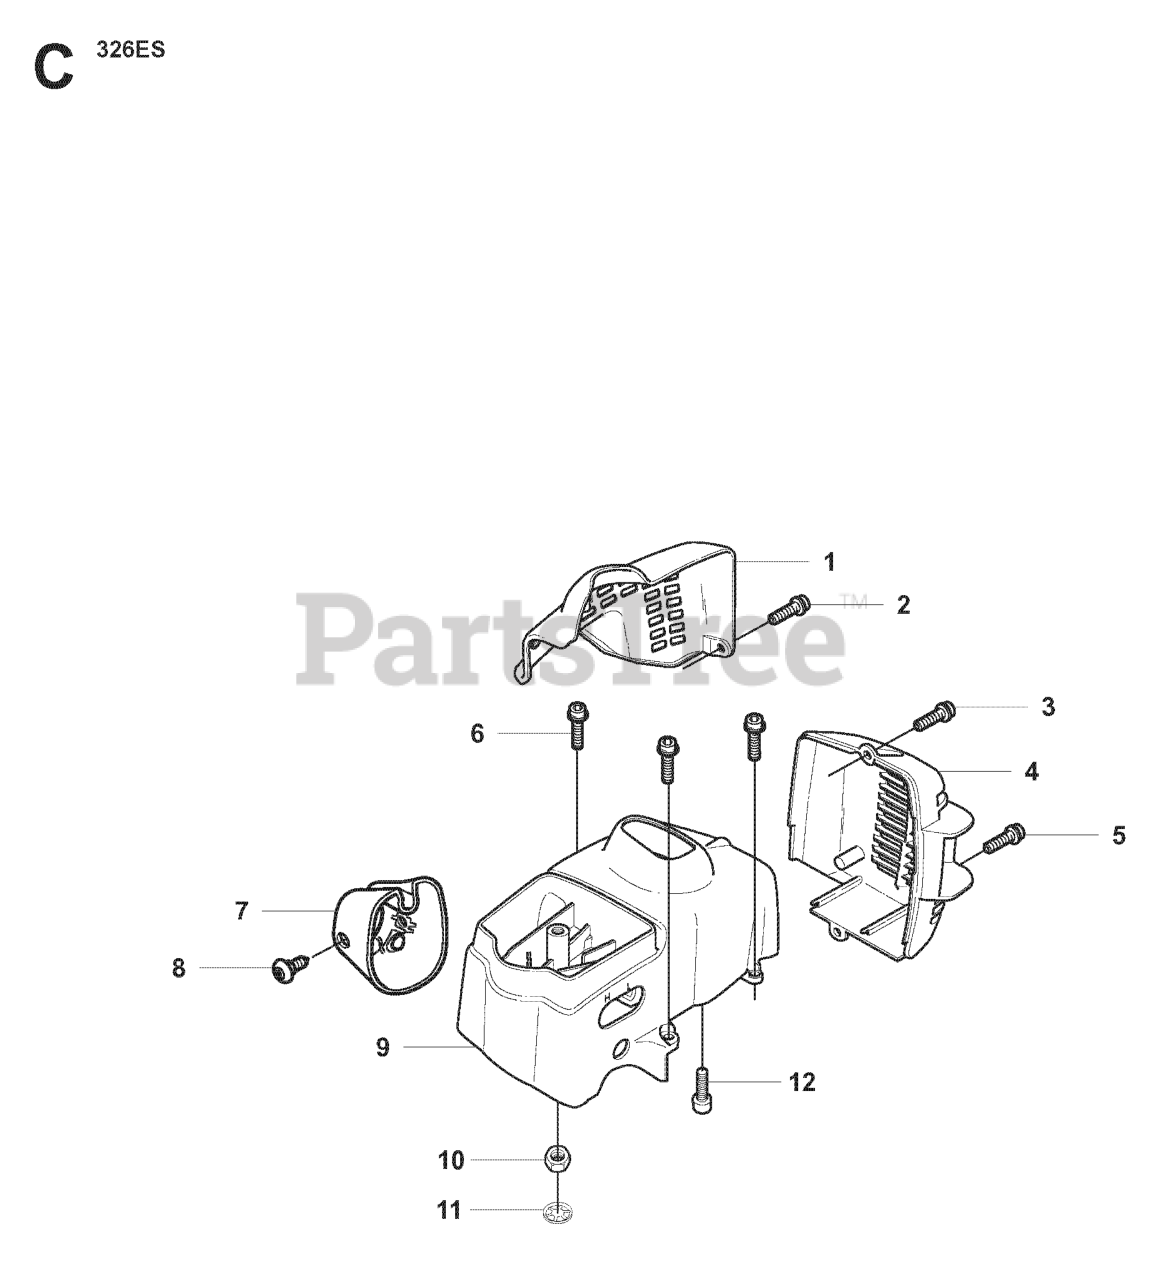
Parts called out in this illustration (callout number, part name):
1	HEAT PROTECTOR, CYLINDER
2	SCREW
3	SCREW
4	GUARD MUFFLER
5	SCREW
6	SCREW
8	SCREW MT5X11
9	CYLINDER COVER
12	SCREW
